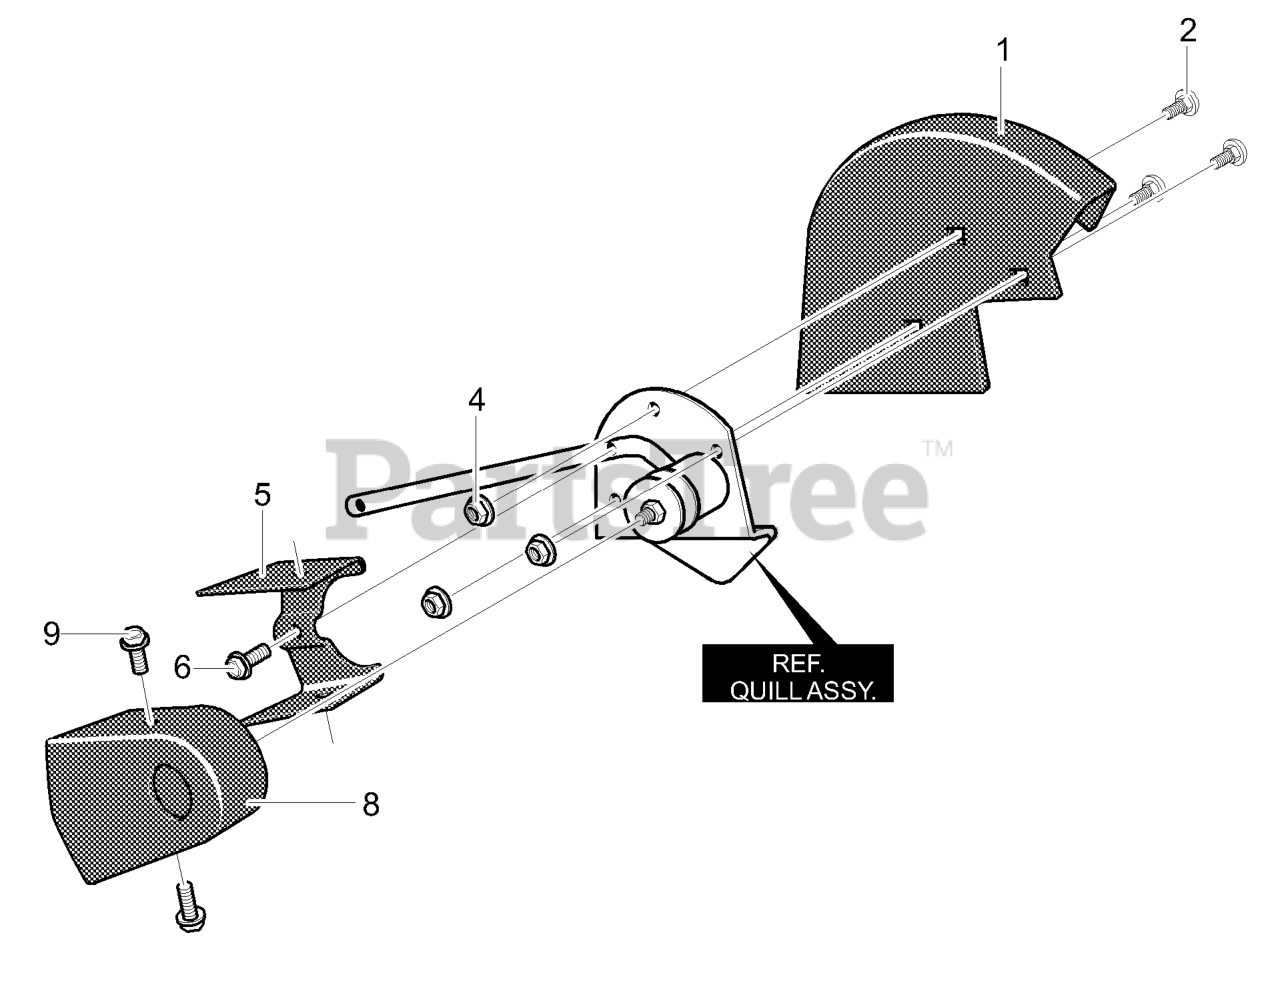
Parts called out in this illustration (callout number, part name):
1	Blade Guard
2	Bolt, 5/16-18x.63 Carr.
4	Nut, 5/16-18 Wdfllk Whiz
5	Guide, Belt Front
6	Screw, 1/4-20x.50
8	Cover, Quill Pulley
9	Screw, 10-16x.50
